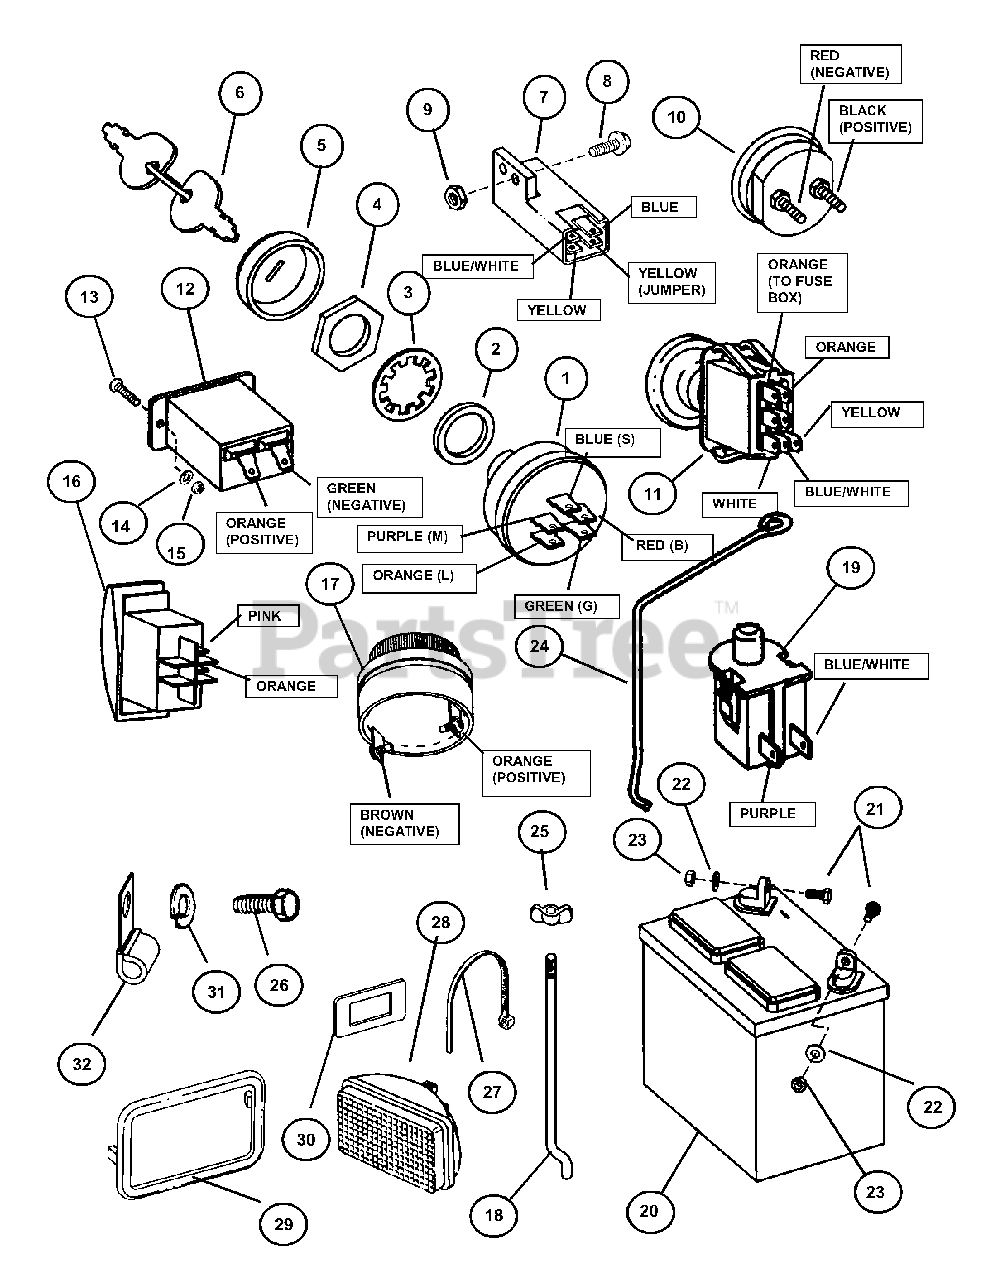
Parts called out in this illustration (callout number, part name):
1	SWITCH, Ignition-After Fire Solenoid
2	SPACER, 5/8"
3	WASHER, 5/8" Internal Tooth Lock
4	NUT, 5/8-32 Hex
5	BEZEL
6	KEY, and Ring
7	SWITCH, DPDT
8	SCREW, #10-32 x 5/8" Hex Machine, Grade. 5
9	NUT, #10-32 Hex Nyloc
10	ASSEMBLY, Ammeter and Clamp
11	SWITCH, PTO
12	HOUR METER, D.C.
13	SCREW, #6-32 x 1/2" Round Head Machine
14	WASHER, #6 Internal Tooth Lock
15	NUT, #6-32 Hex
16	SWITCH, Lights
17	BUZZER, Pulsing
18	BRACKET, Battery Hold Down (1/4-20 Thread)
19	SWITCH, Seat NC
20	BATTERY, 11 Plate- 375CCA
21	SCREW, 1/4-20 x 5/8", Hex Head Cap Gr. 5
22	WASHER, 9/32 I.D. x 5/8 O.D. Flat
23	NUT, 1/4-20 Hex Center Lock Grade B or 5
24	BRACKET, Battery
25	WING NUT, 1/4-20
26	BOLT, 3/8-16 X 1" GD5 CZ
27	CABLE TIE, 7"
28	HEAD LIGHT
29	BEZEL, Headlight
30	SPACER, PTO Switch
31	WASHER, 3/8" SPLIT LOCK
32	CLIP, 3/8" Open Cushioned
